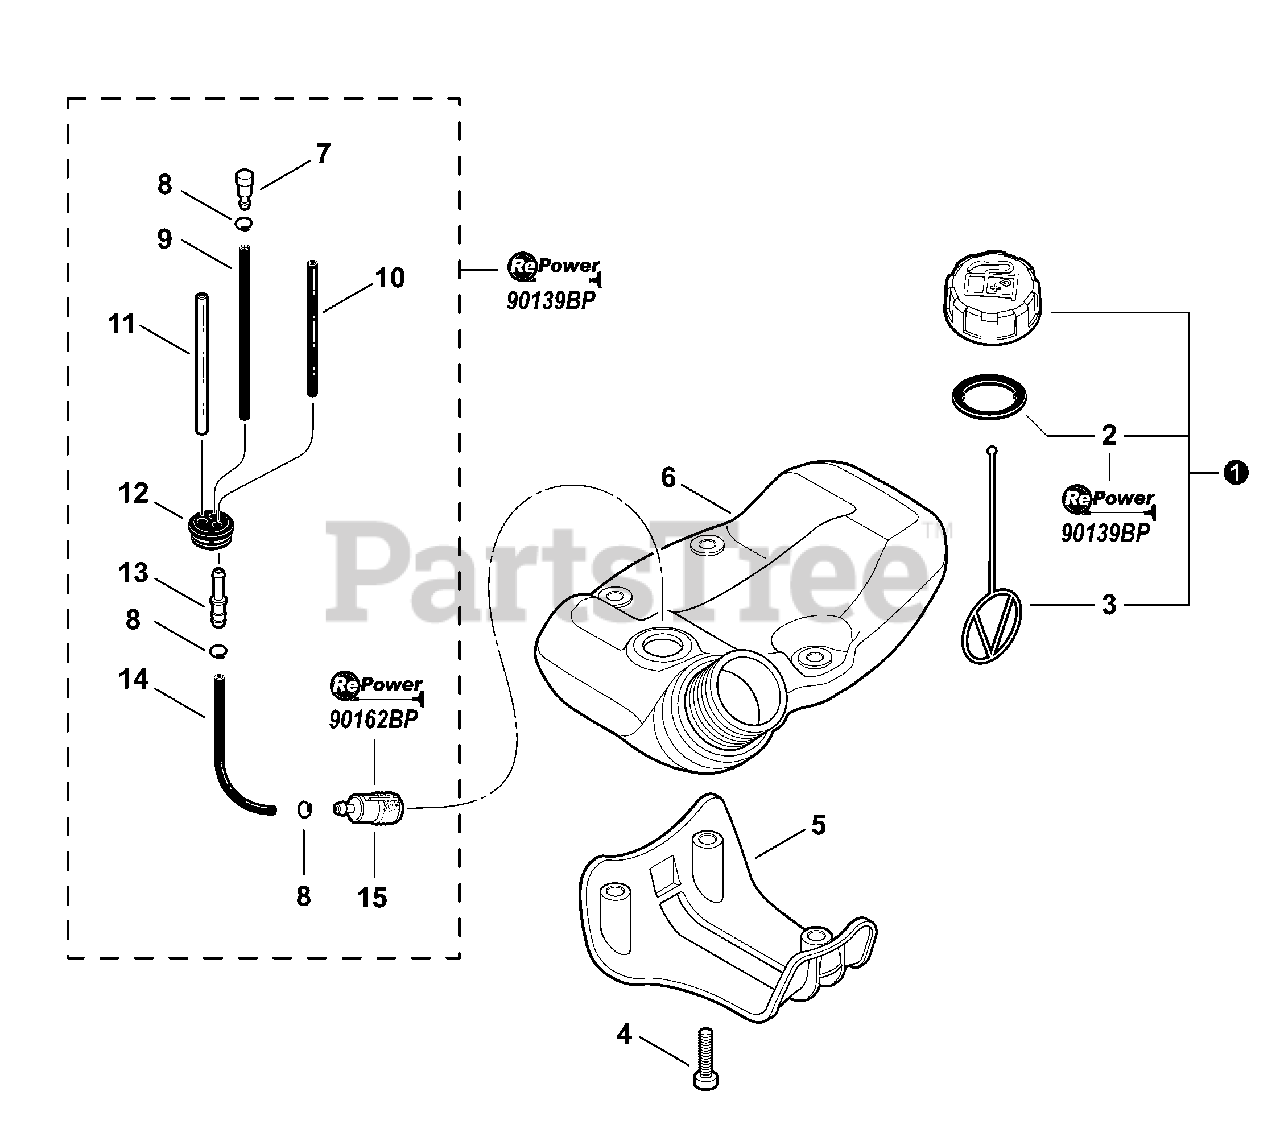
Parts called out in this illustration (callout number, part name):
1	CAP ASY
2	GASKET, CAP
3	CONNECTOR, FUEL CAP
4	SCREW - 5×25
5	GUARD, FUEL TANK
6	TANK, FUEL
7	VENT, FUEL TANK
8	CLIP - 6
9	PIPE - 3×5×90 -- BLACK
10	PIPE - 3×5×74 -- BLACK
11	PIPE - 3×6×80 -- CLEAR
13	CONNECTOR, PIPE
14	PIPE, FUEL -- BLACK
15	FILTER, FUEL
